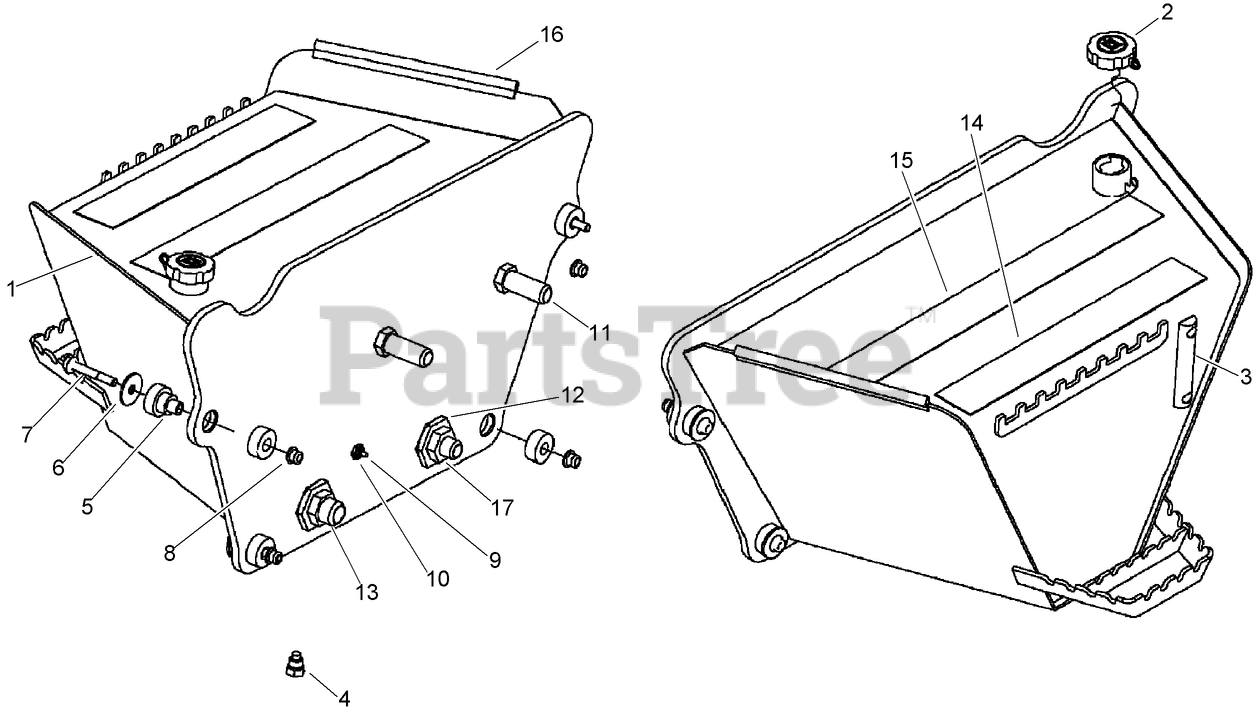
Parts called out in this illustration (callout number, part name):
1	WELDMENT-Hydraulic Tank
2	CAP-HYD FLUID (W/ LOCK)
3	GAUGE-LEVEL, FLUID (W/THERMOMETER)
4	PLUG-HEX, MAGNETIC
5	ISOLATOR-MOUNTING, UNIVERSAL
6	WASHER-FLAT
7	SCREW-HHF
8	NUT-HHF, LOCK
9	SENSOR-SENDER, OIL/WATER TEMP
11	CONNECTOR-Long Str Thkd 1.0, 37FL-ORB 1.0
12	STRAINER-MOUNTED, TANK
13	FITTING-STRAIGHT
14	TAPE-ANTI SKID, LOWER STEP
15	STRIP-ANTI SKID
16	SEAL-Hood
17	ADAPTER-STRAIGHT
